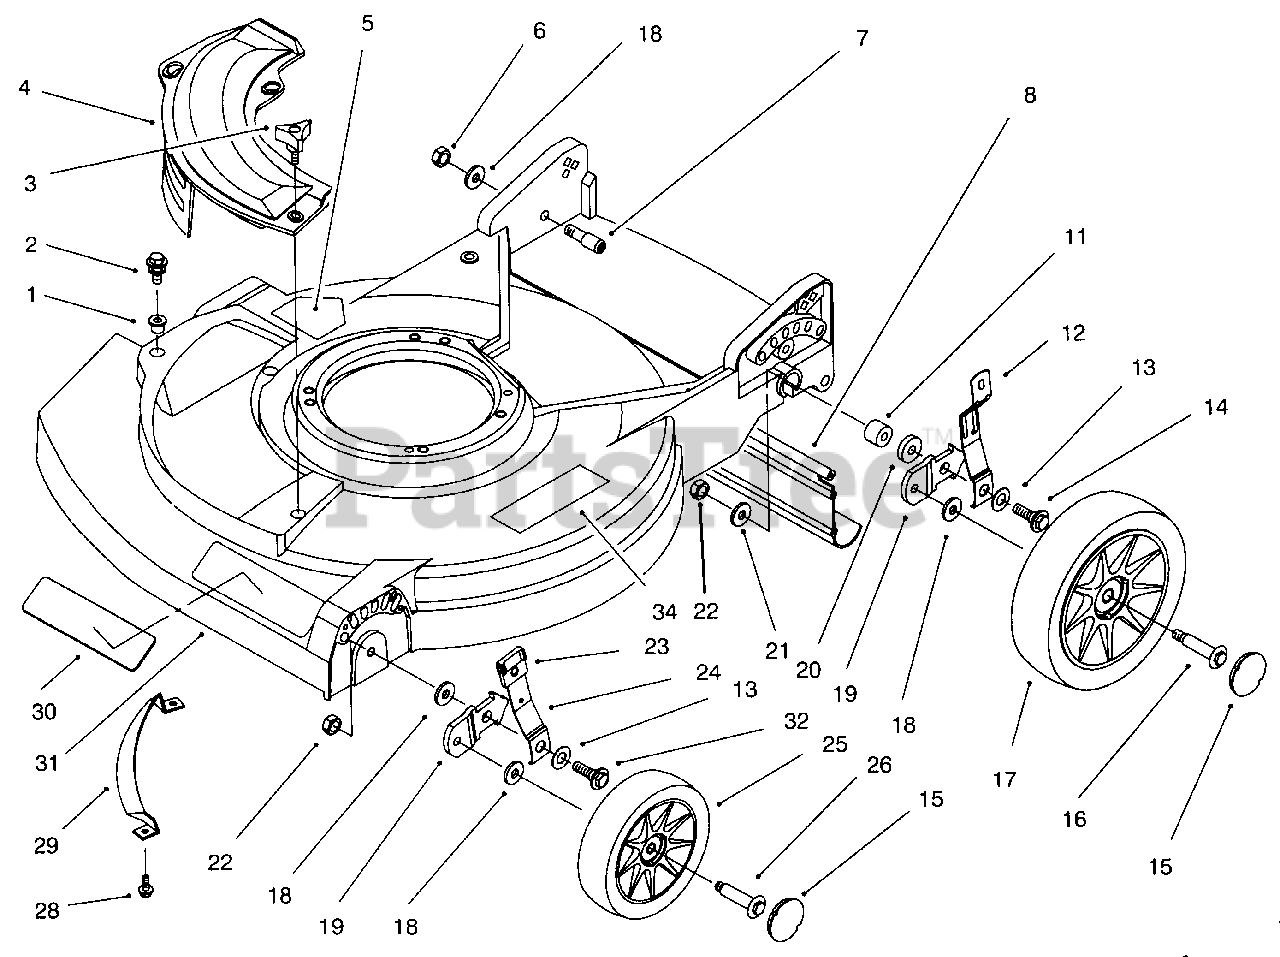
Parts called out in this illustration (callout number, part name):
2	Screw-Thread Form.
3	Knob
4	Cover-Plate, Mulch
5	Decal-Danger
7	Bolt-Shoulder
8	Shield-Trailing
12	Spring Arm Assembly
13	Washer-Belleville
14	Bolt-Shoulder
16	Bolt-Wheel
17	Wheel Assembly 8"
18	Washer Wheel Bolt
19	Bracket-H. O. C.
22	Nut-Lock
23	Knob-Spring Arm
24	Spring Arm Assembly
25	Wheel-6"
26	Bolt-Wheel
29	Bar-Toe
30	Decal-Deck
31	Housing-21" (Incl. Ref. #5, 30 & 34)
32	Bolt-Shoulder
34	Decal-Warning
